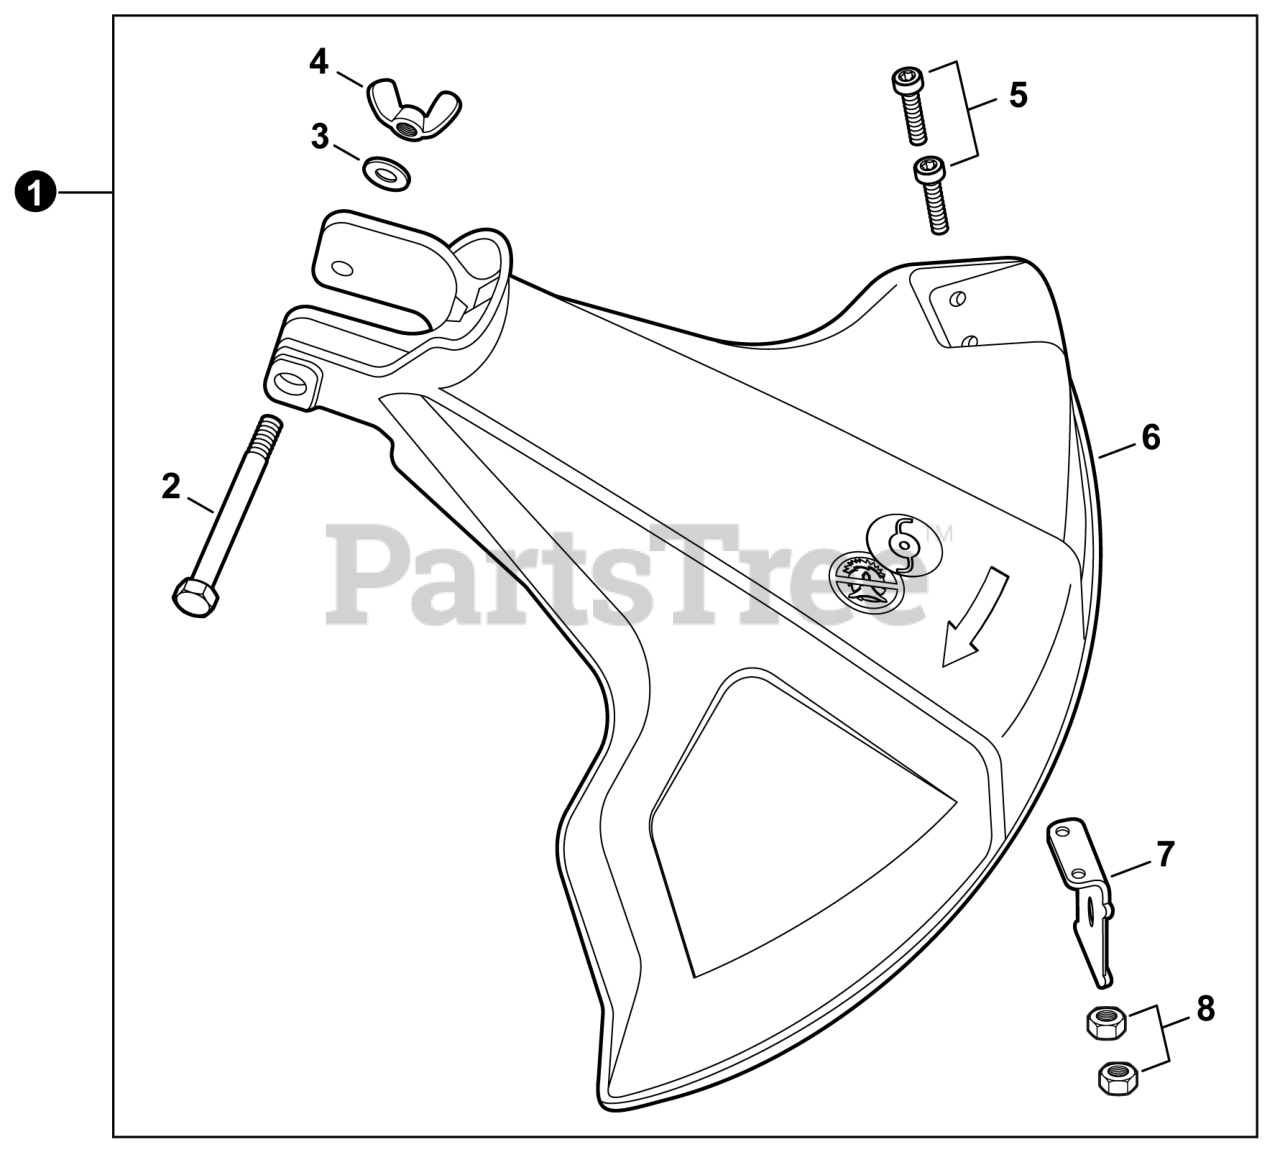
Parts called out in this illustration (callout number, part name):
1	SHIELD KIT
2	BOLT 1/4"-20x2"
3	WASHER 6
4	NUT, WING 1/4"-20
5	SCREW 5x12
6	SHIELD, DEBRIS
7	CUTTER, LINE
